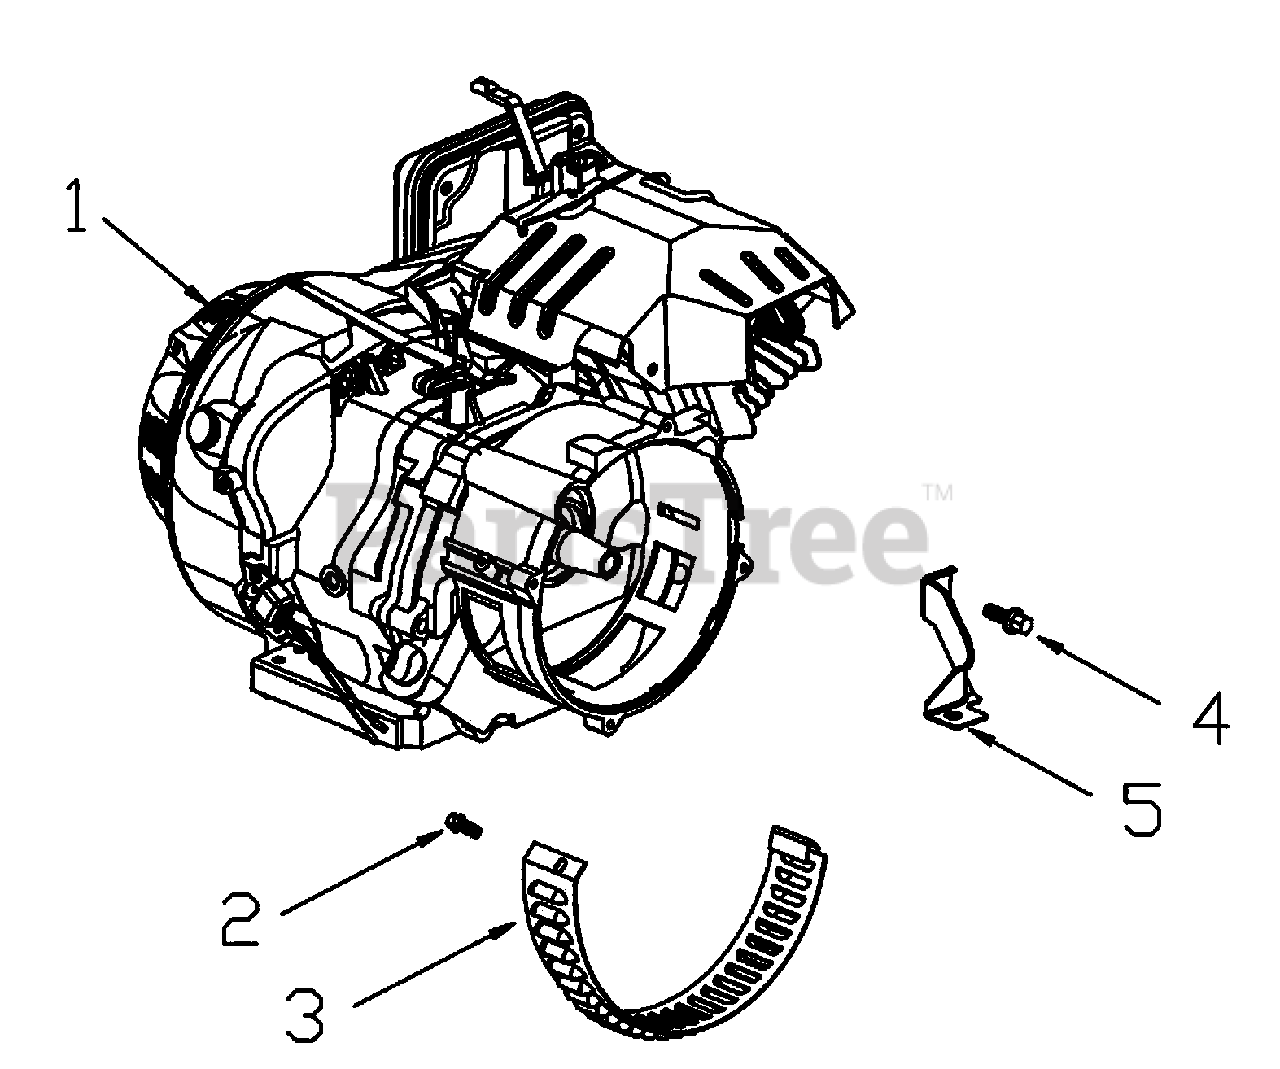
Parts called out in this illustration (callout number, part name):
1	ENGINE, 389CC
2	BOLT, FLANGE M5x10
3	COVER, DUST
4	BOLT, FLANGE M6x12
5	BRACKET,AIR CLEANER
